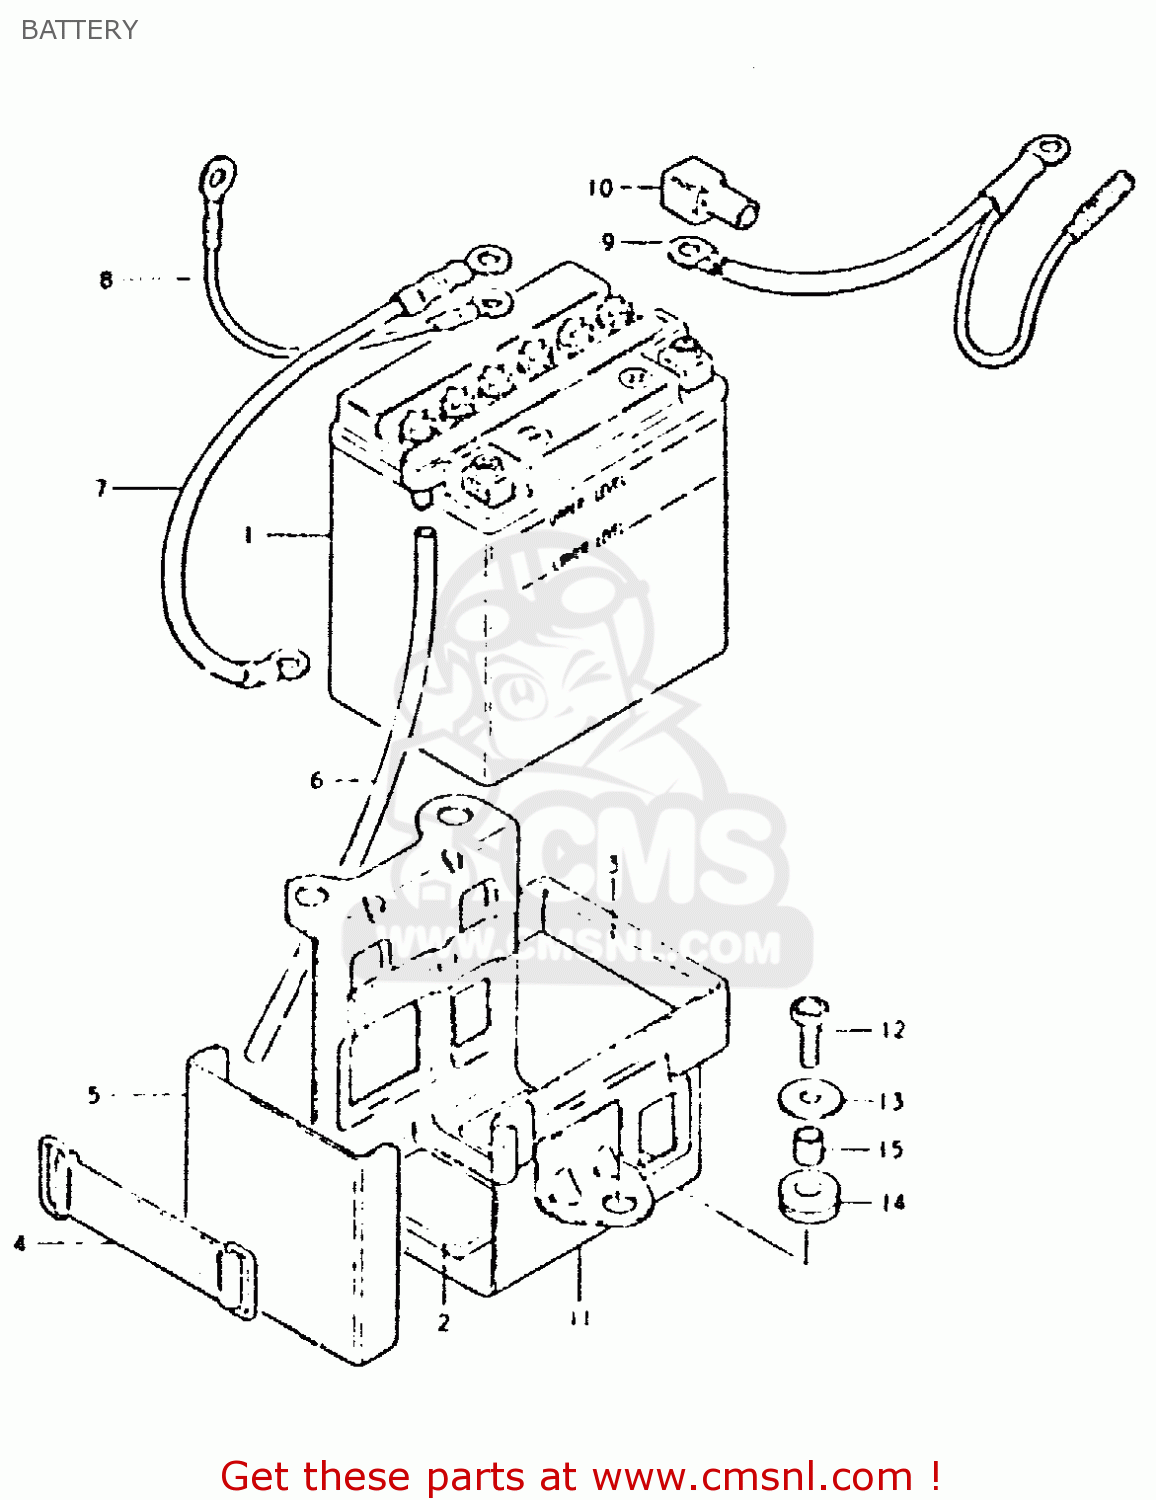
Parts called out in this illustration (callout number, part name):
1	BATTERY ASSY (12V)
2	CUSHION,BATTERY
3	PROTECTOR,20X9
4	BAND
5	COVER,BATTERY
6	HOSE,BATTERY EXHAUST
7	CORD,BATTERY MINUS
8	LEAD WIRE, BODY EARTH
9	WIRE,BATTERY PLUS
10	CAP,TERMINAL
11	HOLDER,BATTERY
12	BOLT
13	WASHER
14	CUSHION
15	SPACER (6.1X9X9)
